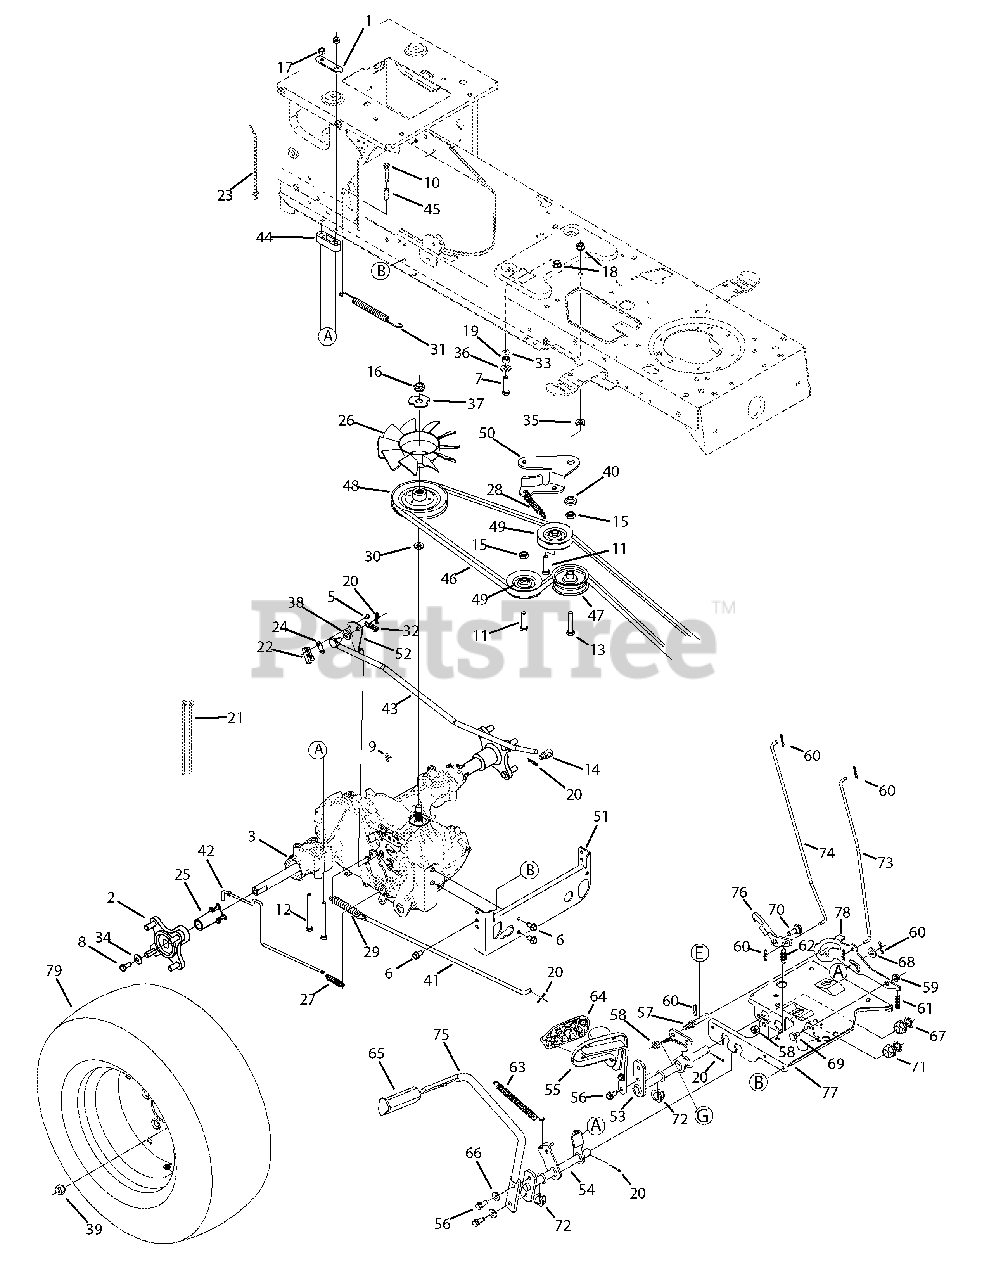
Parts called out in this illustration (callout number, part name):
1	Transmission Mounting Bracket
2	Wheel Hub Assembly
3	Hydrostatic Transmission
5	AB Screw #8-18 x 0.375
6	AB Screw 5/16-18 x 0.75
7	Hex Bolt 3/8-16 x 1.5
8	Screw, 5/16-24 x.750
9	TT Screw 1/4-20 x 0.5
10	Screw, 1/4-20 x 1.50
11	Screw, 3/8-16 x 1.50
12	Hex Bolt 5/16-18 x 3.5
13	Hex Bolt 3/8-16 x 2.25
14	Ferrule
15	Jam Nut 7/16-20
16	Hex Nut, 1/2-20
17	Flange Lock Nut, 5/16-18
18	Flanged Lock Nut 3/8-16
19	Flanged Lock Nut 3/8-16
20	Cotter Pin
21	Cable Tie
22	Switch
23	Cable Tie
24	Insulator Nut Plate
25	Sleeve, .765 x 2.410 Lg.
26	Blade Fan
27	Extension Spring
28	Extension Spring
29	Extension Spring
30	Wire Ring
31	Extension Spring
32	Extension Spring
33	Lock Washer
34	Bell Washer,.340 x.872 x.060
35	Flat Washer,.385 x 1.0 x .135
36	Flat Washer
37	Lock Washer, Hydro Trans.
38	Flat Washer
39	Lug Nut 7/16-14
40	Shoulder Spacer
41	Brake Rod
42	Bypass Rod
43	Control Rod
44	Trans-axle Spacer
45	Spacer,.260 x.372 x 1.030 Lg.
46	V-belt, 4L x 78" Lg
47	Flat Idler Pulley
48	Input Pulley
49	Idler Pulley
50	Idler Bracket
51	Torque Bracket
52	Actuator Bracket
53	Hydrostatic Control Assembly
54	Brake Control Assembly
55	Pedal Assembly
56	LD Screw 5/16-18 x 0.75
58	Flange Lock Nut, 3/8-16
59	Flange Lock Nut, 5/16-18
60	Pin, Cotter
61	Compression Spring
62	Extension Spring
63	Extension Spring
64	Control Pedal
65	Brake Control Pedal
66	Lock Washer 5/16
67	Flat Washer,.64 x 1.24 x.06
68	Flat Washer, .385 x .870 x .092
69	Shoulder Screw
70	Shoulder Screw
71	Hex Flange Bearing
72	Hex Flange Bearing
73	Brake Lock Control Rod
74	Cruise Control Rod
75	Brake Pedal
76	Cruise Latch
77	Steering Support Bracket
78	Hydro Lockout Bracket
79	Tire Only, 22 x 9.5 x 12
